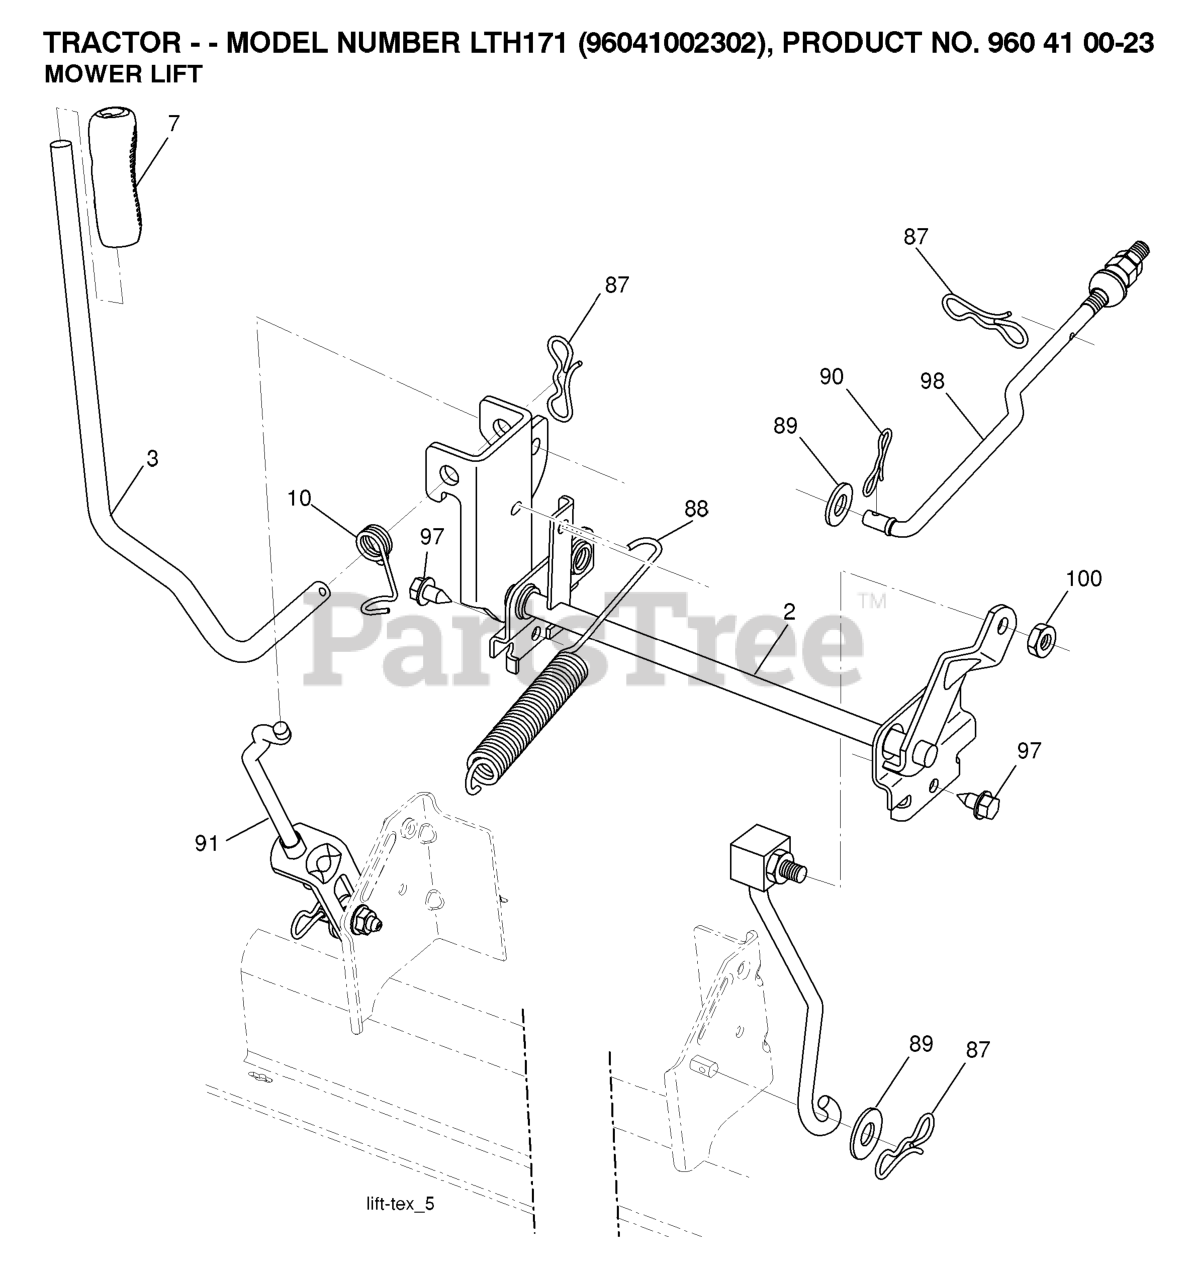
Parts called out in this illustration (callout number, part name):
2	SHAFT.ASM.LIFT.CROSS.H
3	LEVER.LIFT.HANDLE.LT
7	GRIP.HANDLE.LIFT.PVC.BLACK
10	SPRING.TORSION.LIFT.HANDLE
87	PIN.COTTER.7/16.BOW TI.
88	SPRING.LIFT.ASSIST
89	WASHER.CLEAR.ZINC
90	PIN.COTTER.5/16.BOW TI
91	LINK.ASM.LIFT.REAR
97	SCREW, 3/8-16X3/4
98	LINK.ASM.SUSP.FRONT.MW
100	LOCKNUT
